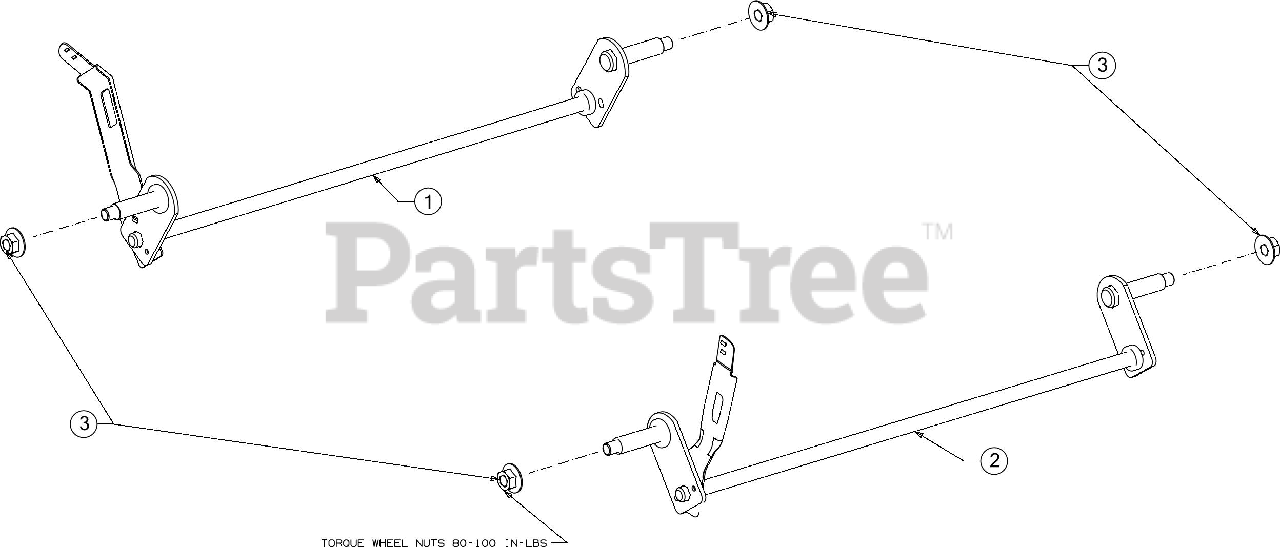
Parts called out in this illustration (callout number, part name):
1	8" REAR AXLE ASSEMBLY
2	7" FRONT AXLE ASSEMBLY
3	FLANGE LOCK NUT
